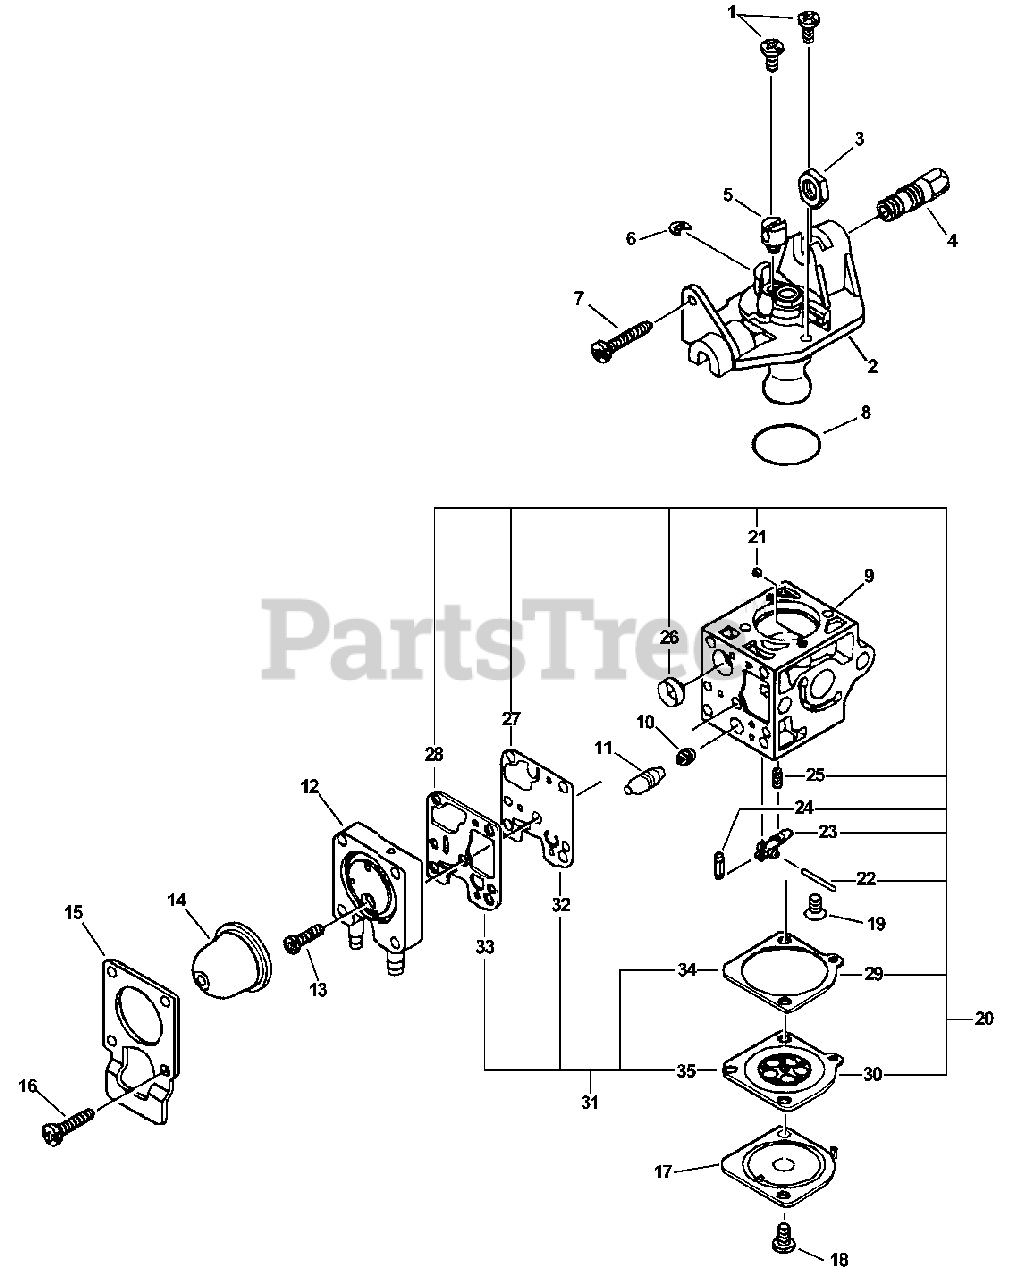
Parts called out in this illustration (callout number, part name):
2	COVER ASSY, ROTOR
4	ADJUSTER, THROTTLE CABLE
7	SCREW, IDLE ADJUST
9	BODY, CARBURETOR
10	JET, MAIN
11	PLUG KIT
12	BASE, PURGE
14	BULB, PURGE
15	RETAINER, PURGE BULB
16	SCREW
17	COVER, METERING DIAPHRAGM
20	REBUILD KIT
21	GUIDE, ROLLER
22	PIN, METERING LEVER
23	LEVER, METERING
24	VALVE, INLET NEEDLE
25	SPRING, METERING LEVER
26	STRAINER
27	DIAPHRAGM, PUMP
28	GASKET, PUMP
29	GASKET, DIAPHRAGM
30	DIAPHRAGM, METERING
31	GASKET / DIAPHRAGM KIT
32	DIAPHRAGM, PUMP
33	GASKET, PUMP
34	GASKET, DIAPHRAGM
35	DIAPHRAGM, METERING
